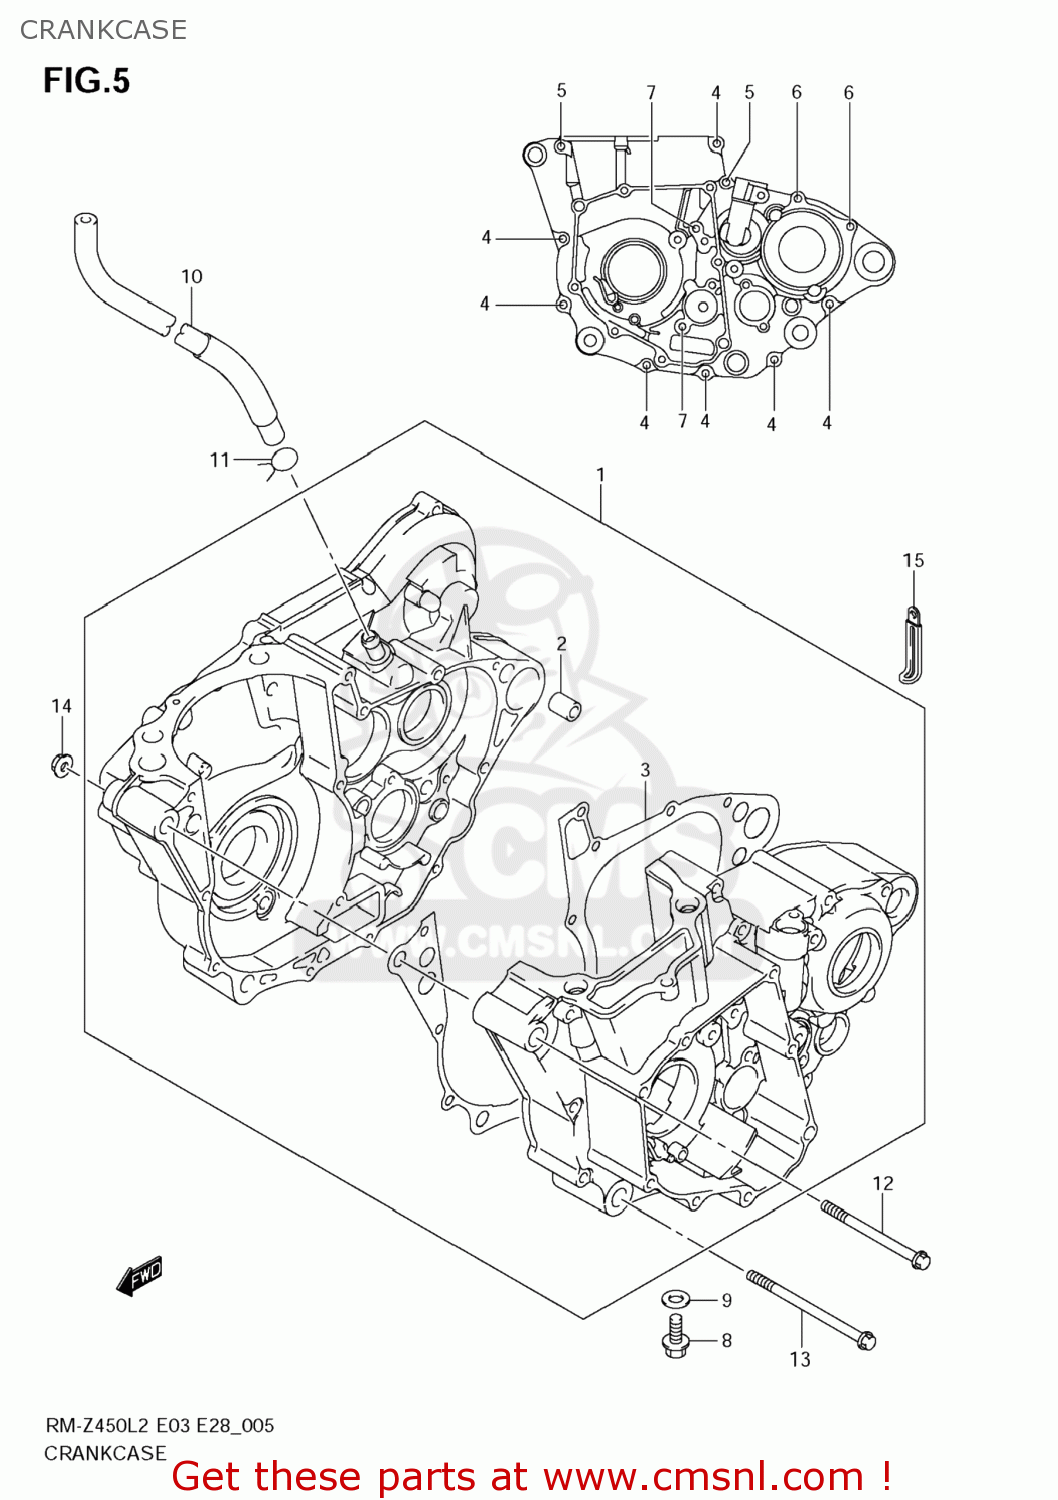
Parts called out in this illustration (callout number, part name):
1	CRANKCASE SET
2	PIN(10.4X13X18)
3	GASKET,CRANKCASE (NAS)
4	BOLT
5	BOLT
6	BOLT
7	BOLT
8	BOLT(8X20)
9	GASKET(8.2X14X1) (NAS)
10	HOSE,BREATHER
11	CLIP
12	BOLT(10X135)
13	BOLT(10X125)
14	NUT
15	CLAMP(L:45)
